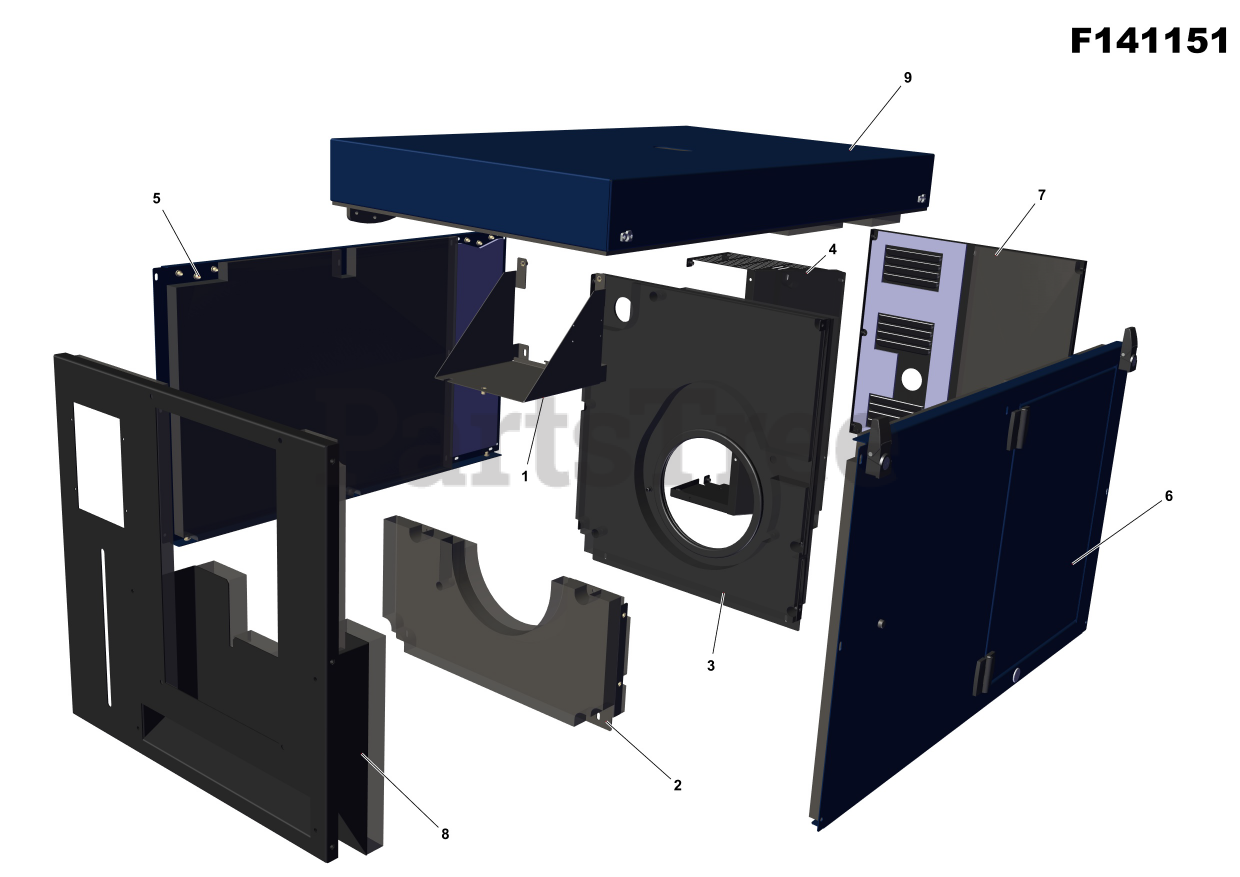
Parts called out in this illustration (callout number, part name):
2	DEFLECTOR
3	DEFLECTOR
4	DEFLECTOR
6	RIGHT PANEL
7	FRONT PANEL
8	REAR PANEL
